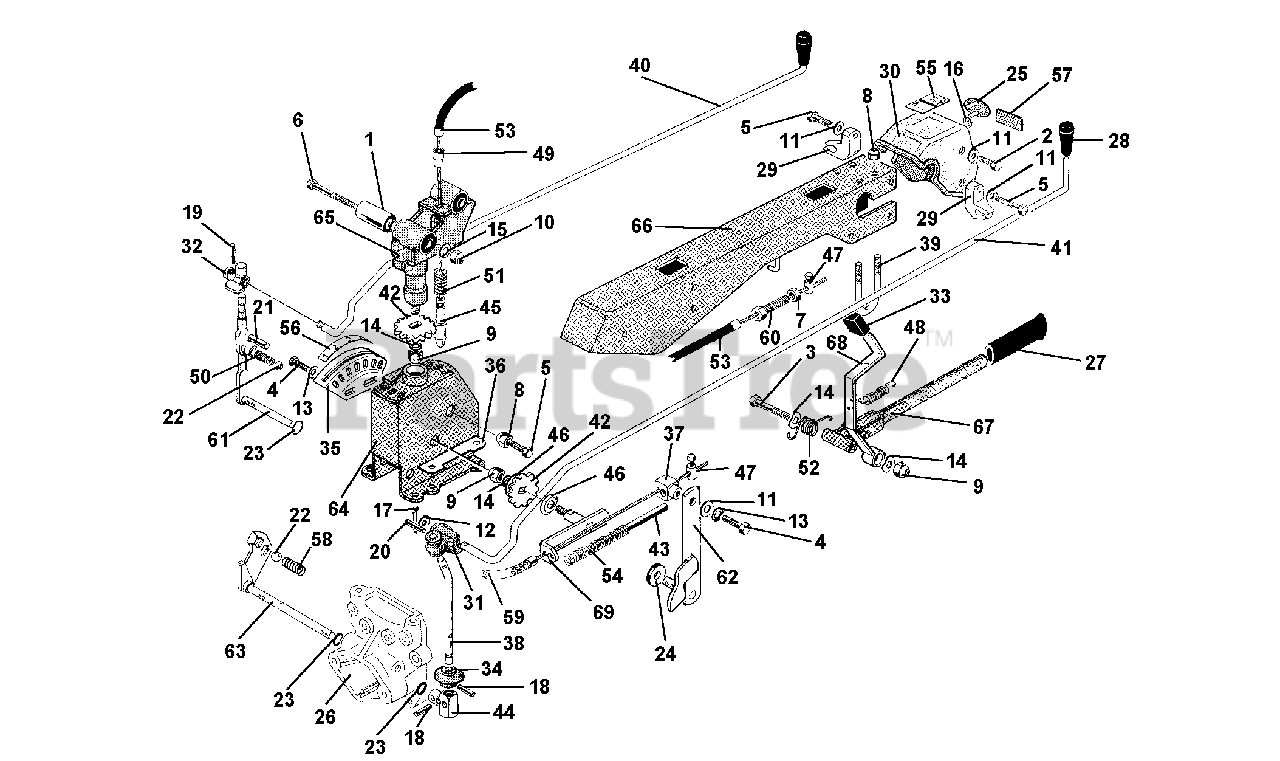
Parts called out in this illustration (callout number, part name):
2	SCREW M8 X 16
3	SCREW TE M10 X 90
4	SCREW M8 X 12
5	SCREW M8 X 35
6	SCREW TE M12 X 95 UNI 5739 8G
8	NUT, SELF LOCKING M8
9	NUT, SELF LOCKING M10 LOW
10	NUT, SELF LOCKING M12 LOW
11	WASHER, FLAT 8.4
12	WASHER P10.5 X 18
13	WASHER, LOCK 8.4
14	WASHER, LOCK 10.5
15	WSHER, LOCK 13
16	WASHER, LOCK FOR PINS
18	LOCKING PIN 4 X 20 SPIRAL
19	PIN, LOCKING SW 3 X 22 SPIRAL
20	LOCKING PIN 4 X 24 SPIRAL
21	LOCKING PIN SPIRAL
22	BALL 15/32 RIV RB-11.906
23	O-RING 115 11.91 X 2.62
24	SEAL, OIL 12 X 19 X 5 STANDARD
29	SUPPORT CONTROL ROD CUT
30	STEERING COLUMN INSTRUM.PANEL
31	GEARBOX ARTICULATION
32	GEARBOX ARTCULATION
33	KNOB REDUCTION UNIT LEVER
34	P.T.O. STOP RING
35	GEARBOX SELECTOR
36	REVERSE SPEED LEVER DOG
37	REVERSER BLOCK
38	PTO CONTROL LEVER
39	HANDLEBAR U-BOLT
40	GEARBOX CONTROL ROD
41	PTO CONTROL ROD
42	REVERSE GEAR
44	P.T.O. JOINT
45	STEERING COLUMN PIN
46	PROTECTION END D 32
47	CLAMP, CABLE
48	LEVER RETURN SPRING
49	END, SHEATH
51	STEERING COLUMN RELEASE SPRING
52	HANDLEBAR RELEASE SPRING
53	WIRE AND SHEATH L 90
54	REVERSER SPRING
55	STEERING COLUMN STICKER
56	SPEED STICKER
57	STICKER 605
58	P.T.O. SPRING
59	SHEATH CABLE
60	ADJUSTING SCREW
61	GEARBOX LEVER
62	REVERSER LEVER
64	STEERING COLUMN SUPPORT
65	STEERING COLUMN COUPLING
66	STEERING COLUMN
67	HANDLEBAR RELEASE LEVER
68	STEERING COLUMN LOCKING LEVER
69	REVERSER POSITION LEVER
